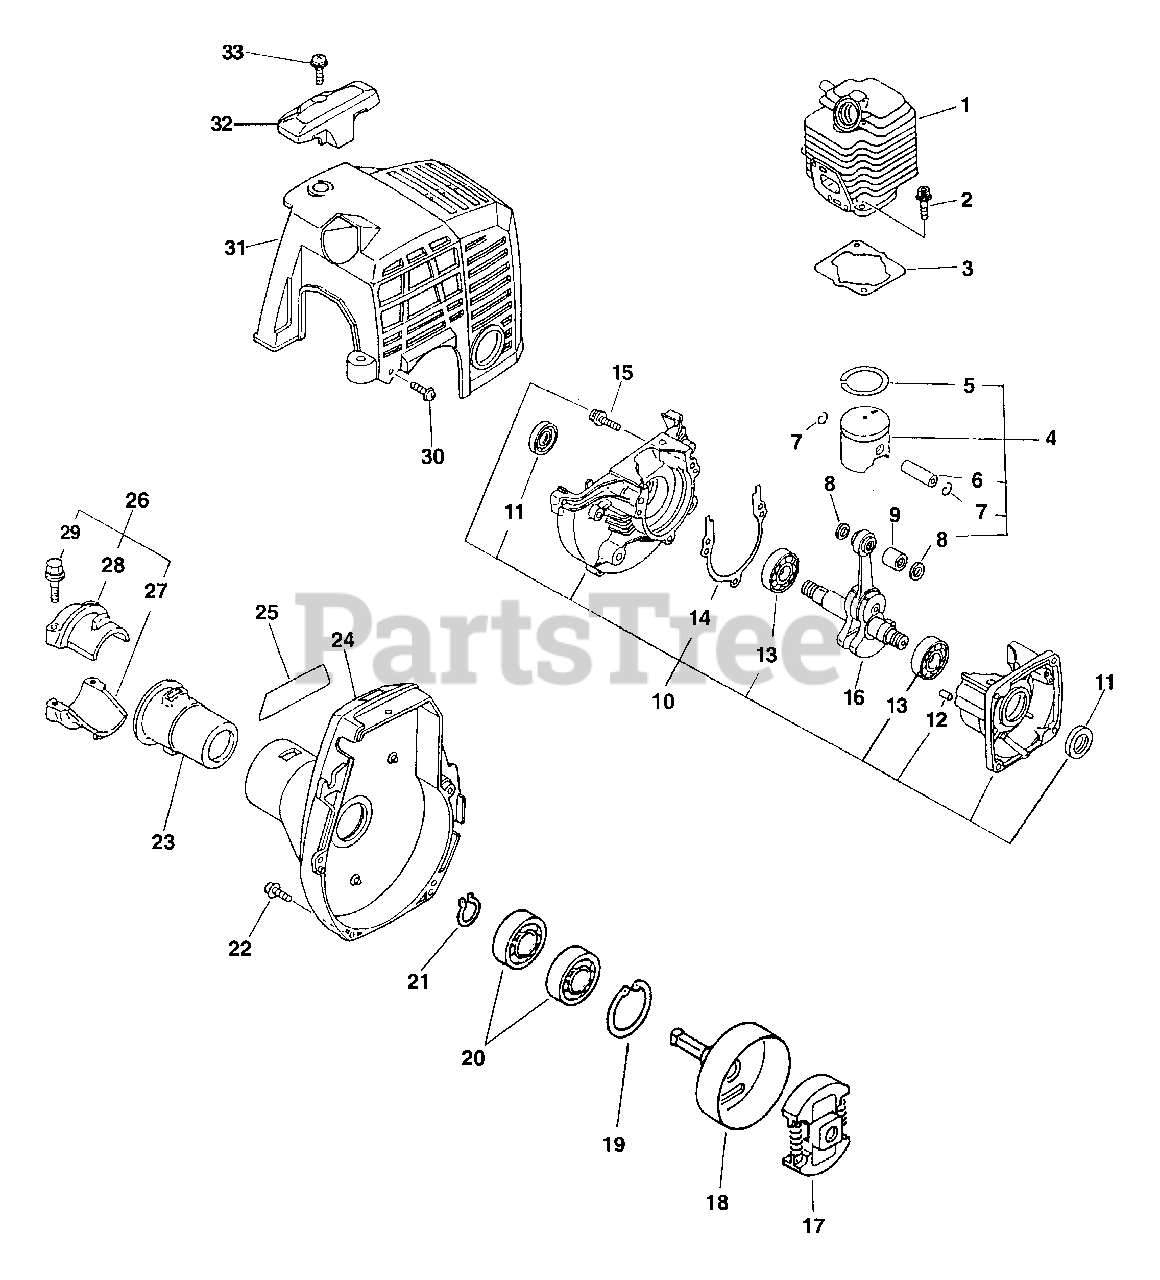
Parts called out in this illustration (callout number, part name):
1	CYLINDER/PISTON KIT
2	BOLT 5×22
3	GASKET, CYLINDER
4	PISTON KIT
5	RING, PISTON
6	PIN, PISTON 8
7	RING, SNAP
8	WASHER, THRUST
9	BEARING, NEEDLE
10	CRANKCASE KIT
11	SEAL, OIL 12
12	PIN, LOCATING 4
13	BEARING, BALL - 6201 C3
14	GASKET, CRANKCASE
15	BOLT 5×28
16	CRANKSHAFT ASSY
17	CLUTCH ASSY
18	DRUM, CLUTCH
19	RING, SNAP 28
20	BEARING, BALL 6001
21	RING, RETAINING - 12
22	BOLT 4×16
23	CUSHION Ø25
24	COVER ASSY, FAN
25	LABEL, MODEL
26	RETAINER KIT
27	HOLDER - LOWER
28	HOLDER, MAIN PIPE - UPPER
29	BOLT - 5×25
30	BOLT 4×16
31	COVER, ENGINE
32	GUARD, TOP
33	SCREW 5×16
34	SHORT BLOCK - SB1024
35	GASKET KIT
